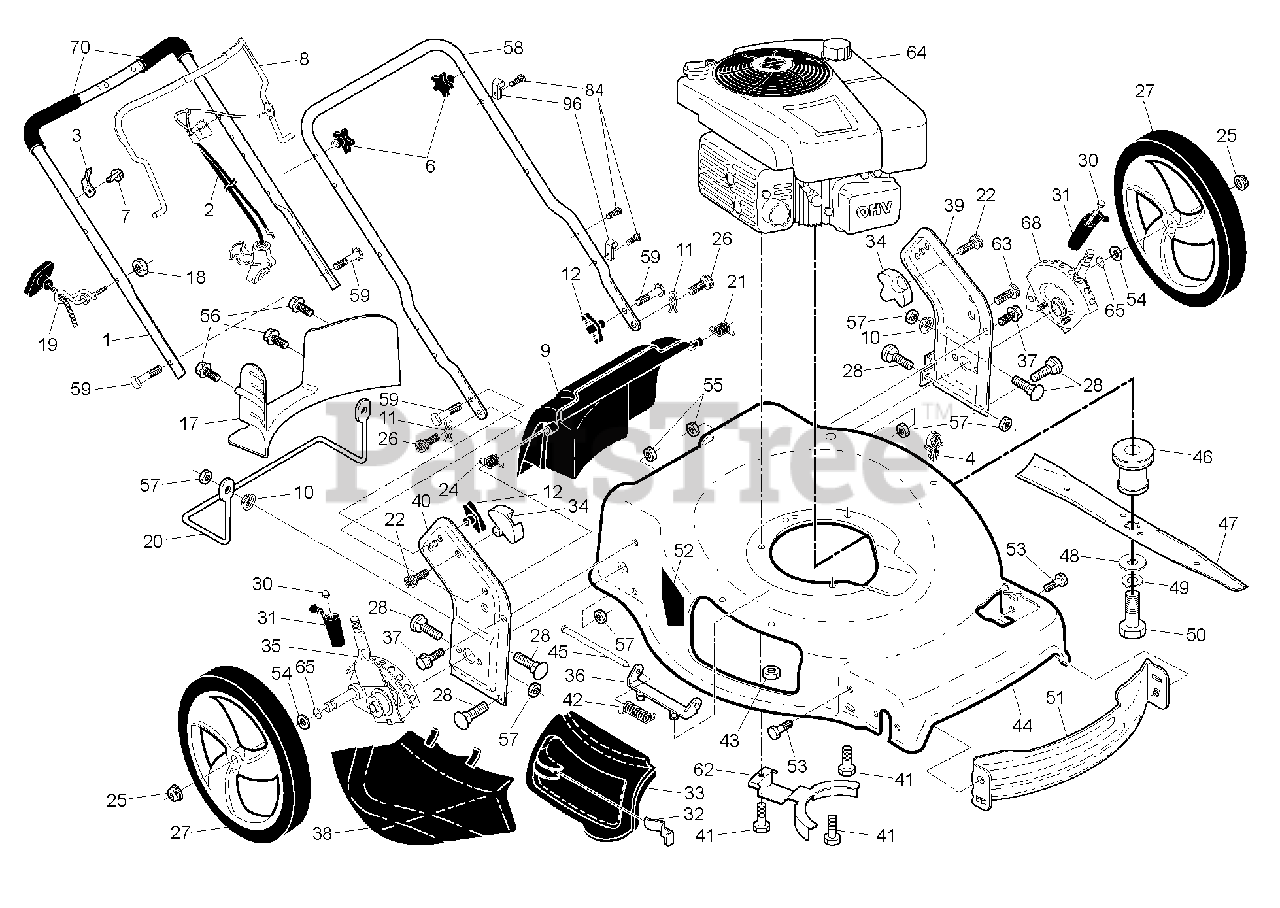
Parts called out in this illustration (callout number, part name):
2	CABLE.ASM
3	BRACKET.UPSTOP.RT
4	PUSH CLIP
5	TIE GUIDE
6	KNOB.HANDLE.PLASTIC.STAR.BLACK
11	COTTER.HAIRPIN.DOOR/HANDLE.PIV
12	KNOB, DEFLECTOR
18	NUT
19	GUIDE.ROPE.STD.BLK.ZIN
21	SPRING.LH.GRAY
22	SCREW.PAN.HEAD.#10
24	SPRING.RH.GRAY
25	NUT.HEX.FLANGE.3/8-16.LOCKNUT
26	SCREW,DOOR/HANDLE.PIVOT
28	BOLT
36	HINGE BRACKET ASSEMBLY
37	BOLT.HEX.HD.WASHER.5/16-18X.75
38	DEFLECTOR.CLIPPING.22.BLACK
41	BOLT 3/8-16X1-1/8
42	SPRING.TORSION
43	NUT.HEX.FLANGE.1/4
45	ROD.HINGE.21
46	ADPTER.BLAD.25M.VS.22PLU.STAR
48	WASHER,HARDEN
49	LOCKWASHER
50	SCREW, HEX HD 3/8-24 X 1-3/8
52	DECAL.INTERNATIONL.CUTFINGER
53	BOLT.5/16HEX.WHS.HD
54	WASHER PM
55	NUT.HEX.FLANGE.1/4
56	SCREW.HX.13X.750
57	NUT.FLANGE.5/16
59	BOLT, HANDLE 5/16-18X1.75
62	BRACKET.ENG/BELTKEEPER
65	O-RING..070X.487.NEOPRENE
70	GRIP.HANDLE.FOAM.WIDE.(1 SIDE)
84	FASTENER.PUSH.O.250X0.783
96	CLIP.CABLE.BLK
